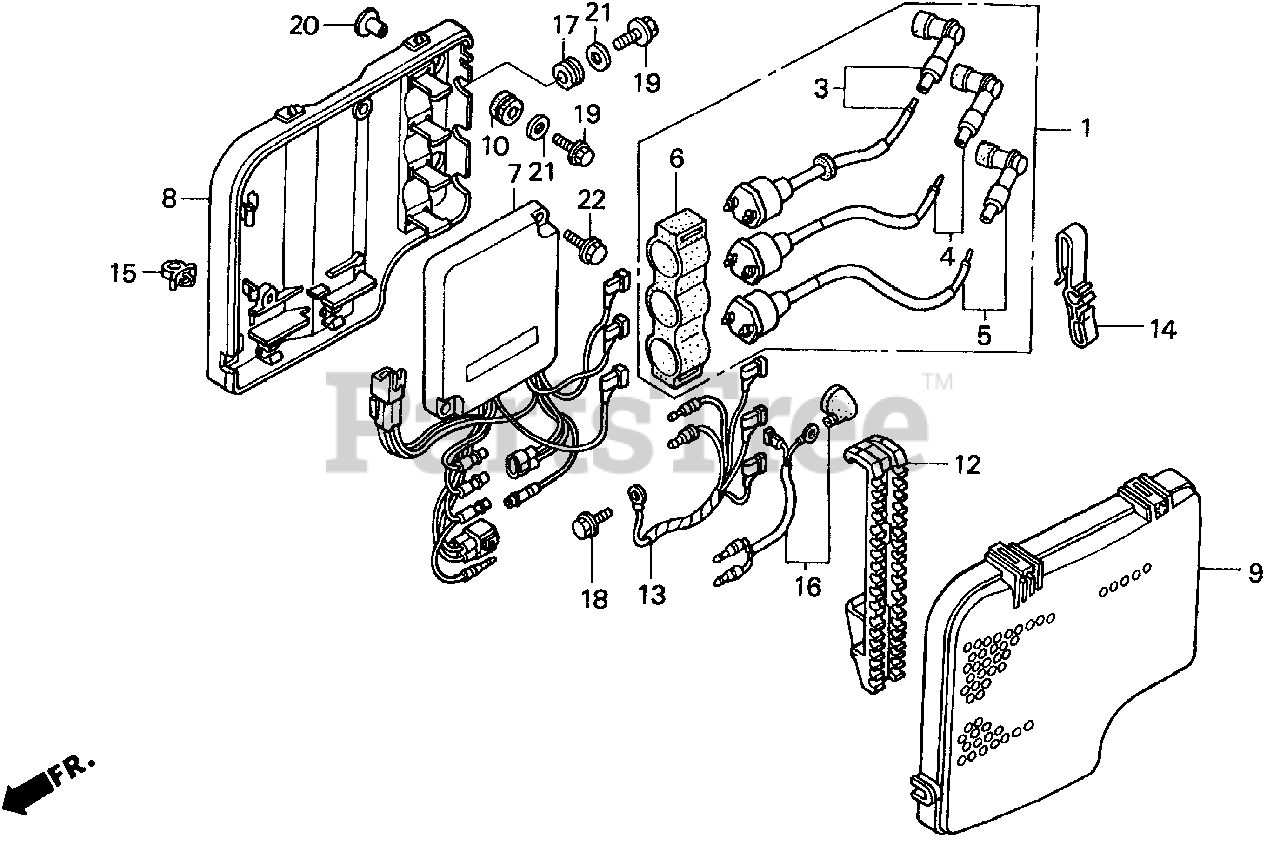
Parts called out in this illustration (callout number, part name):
1	COIL ASSY., IGNITION
3	COIL, IGNITION (1)
4	COIL, IGNITION (2)
5	COIL, IGNITION (3)
6	SUSPENSION, IGNITION COIL
7	MODULE ASSY., IGNITION CONTROL (CDI)
8	CASE, IGNITION CONTROL MODULE
9	COVER, IGNITION CONTROL MODULE
9	COVER, IGNITION CONTROL MODULE (CDI)
10	GROMMET, IGNITION CONTROL MODULE CASE (B)
12	BRACKET, CONNECTOR (A)
13	WIRE ASSY., GROUND
14	CLAMP, CENTER WIRE
15	CLIP, TURN SIGNAL WIRE
16	WIRE, SWITCH
17	GROMMET, CASE (LOWER)
18	BOLT, FLANGE (6X12)
19	BOLT, FLANGE (6X25)
20	COLLAR, IGNITION CONTROL MODULE CASE
20	COLLAR, MODULE IGNITION CONTROL CASE (CDI)
21	WASHER, PLAIN (6MM)
22	BOLT, FLANGE (6X20)
